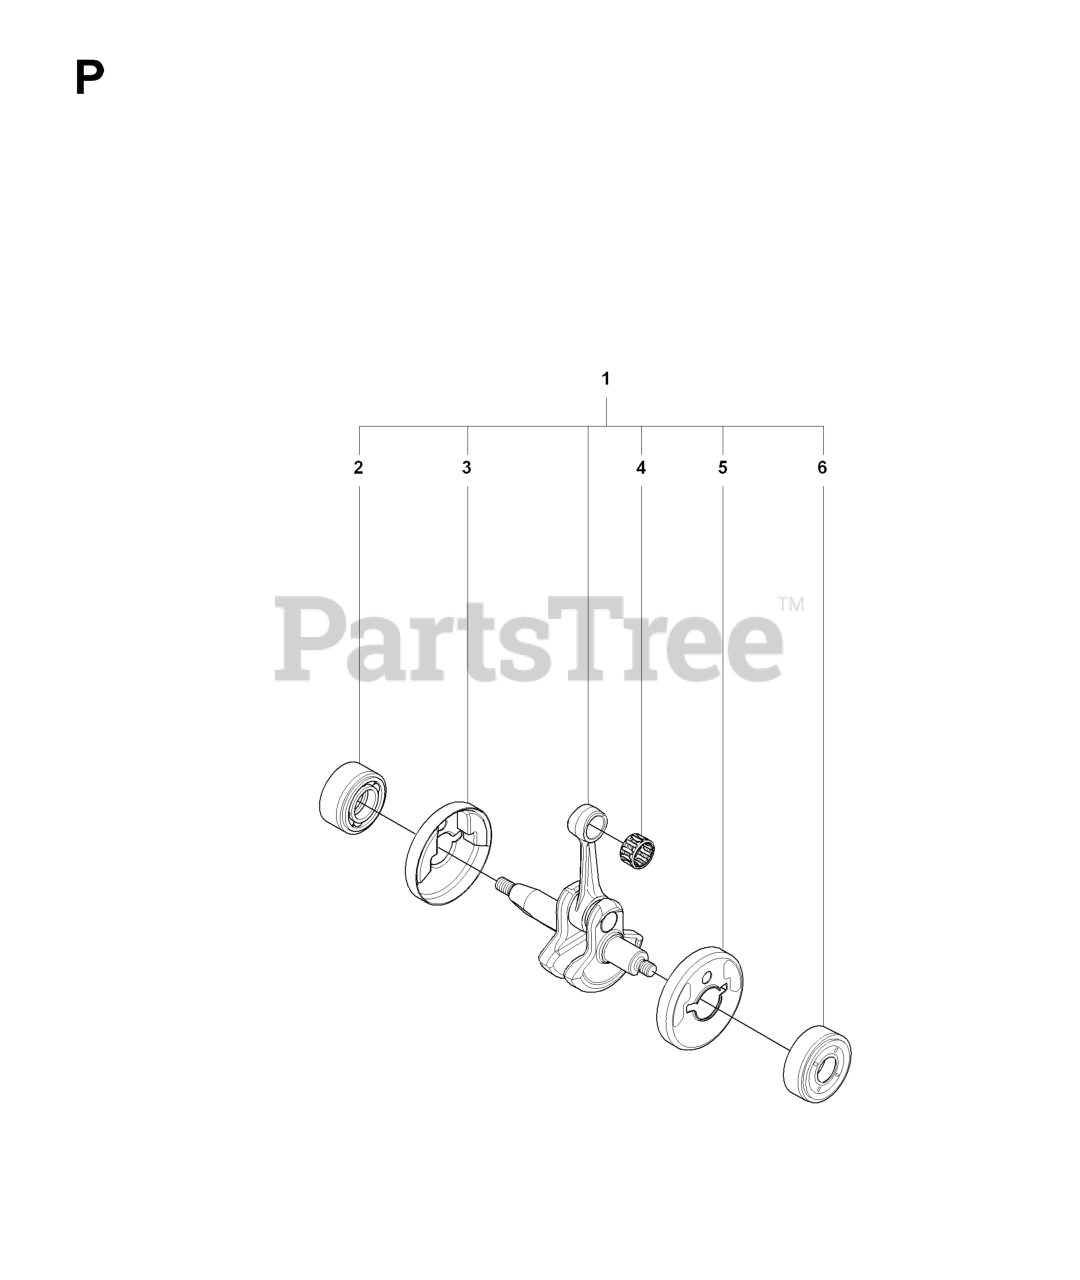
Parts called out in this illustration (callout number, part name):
1	CRANKSHAFT
2	BEARING CAP
6	BEARING CAP
